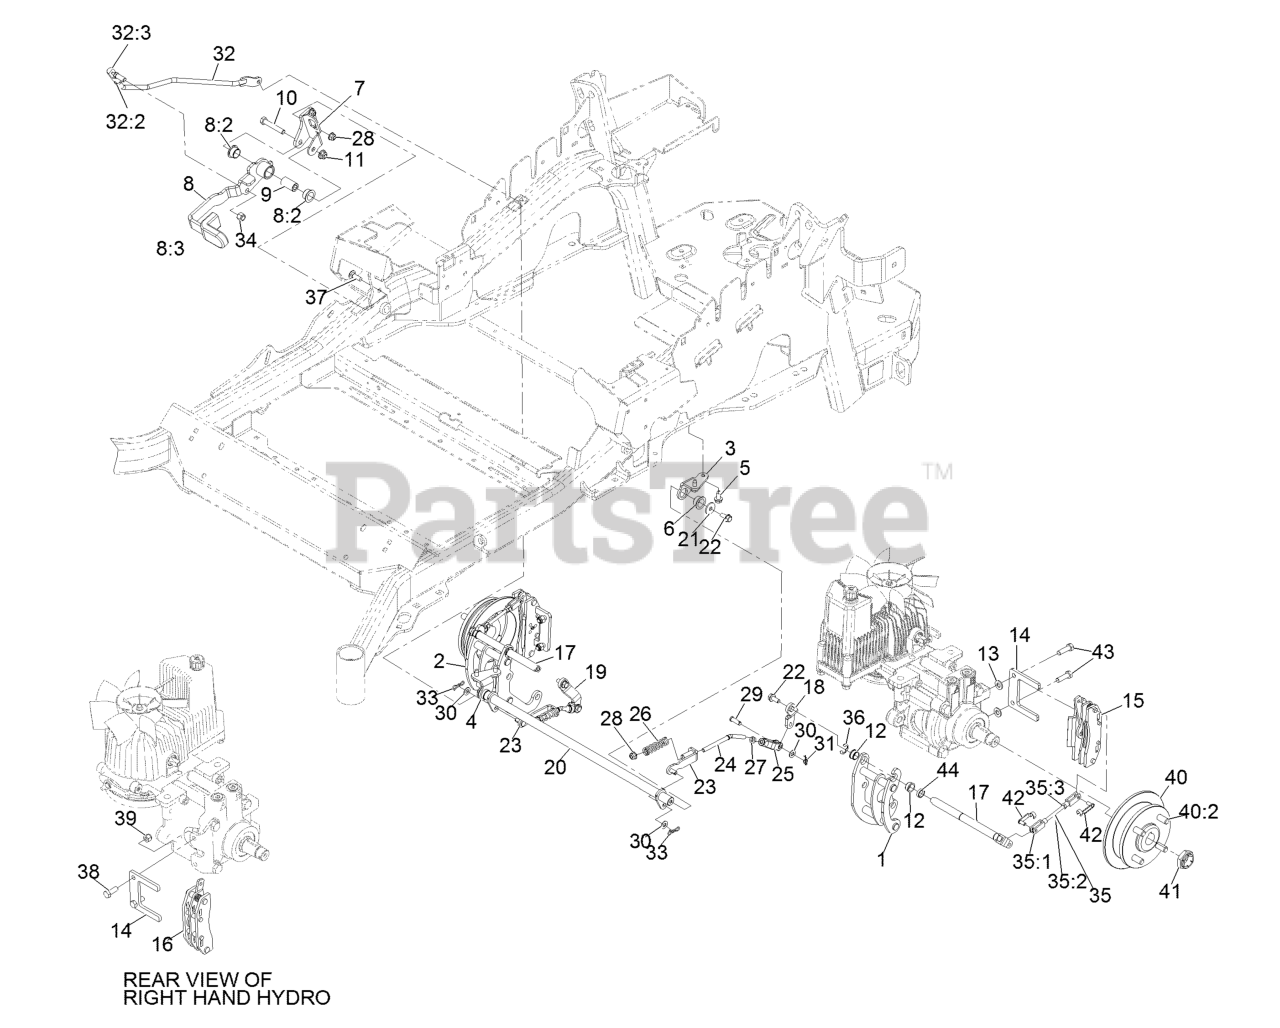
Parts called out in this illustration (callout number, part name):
1	Mount-Bellcrank, LH
2	Mount-Bellcrank, RH
3	Mount-Pivot, LH
4	Mount-Pivot, RH
5	Screw-HWH 5/16-18 X 3/4 Tf
6	Bushing-Flanged
7	Bracket-Mount
8	Brake Lever ASM W/ Grip
8:2	Bushing-Flanged
8:3	Grip-Lever
9	Handle-Pivot, Brake
10	Screw-HH 3/8-16 X 2 1/4
11	Nut-Nyloc 3/8-16 Flg
12	Bushing
13	Washer-3/8 SAE
14	Plate-Mount, Brake
15	Caliper-Brake
16	Caliper-Brake, RH
17	Bellcrank
18	Arm-Inner, LH
19	Arm-Inner, RH
20	Shaft-Cross
21	Washer-Flat
23	Bracket-L
24	Linkage-Mid
25	Yoke-Offset
26	Spring-Compression
27	Nut-Jam 5/16-24
28	Nut-Nyloc 5/16-18 Flg
29	Pin-Clevis 5/16 X 1 49/64
30	Washer-5/16 SAE
31	Pin-Cotter, Locking
32	Front Linkage ASM
32:2	End-Tie Rod, RH
32:3	Nut-Jam 3/8-24
33	Pin-Cotter, Locking
34	Nut-Nyloc 3/8-24
35	Rear Linkage ASM
35:1	Yoke
35:2	Linkage, Rear
35:3	Nut-Jam 1/4-28
37	Bolt-Carriage 5/16-18 X 1
38	Screw-HH 3/8-16 X 1
39	Nut-Nyloc 3/8-16
40	Wheel Hub ASM
40:2	Stud-Wheel
41	Locknut
42	Pin-Clevis, Spring
43	Screw-HH 3/8-16 X 1 1/4 Patch Lock
